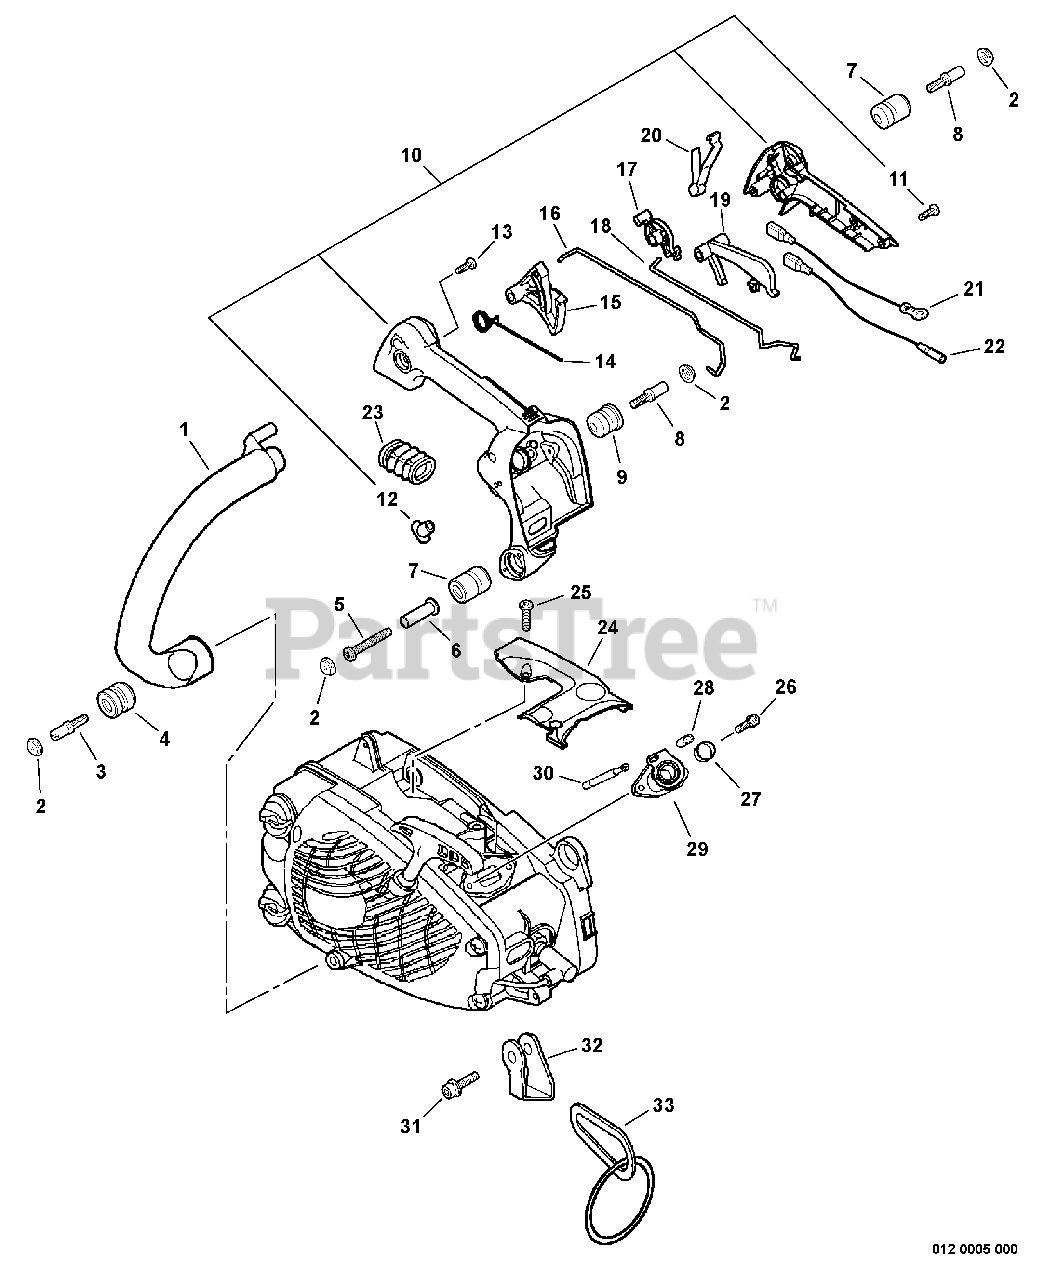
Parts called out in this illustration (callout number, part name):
1	HANDLE - FRONT
2	CAP, CUSHION
5	SCREW - 4X35 -- TAPPING
7	CUSHION
8	STUD, THREADED
9	CUSHION
10	HANDLE SET - REAR
11	SCREW - 4X16
13	SCREW - 5X20 -- TAPPING
14	SPRING, TRIGGER
15	TRIGGER, THROTTLE
16	ROD, THROTTLE
17	LEVER, CHOKE
18	ROD, CHOKE
19	LEVER, TRIGGER LOCKOUT
20	TERMINAL - GROUND
21	LEAD - GROUND
22	LEAD - IGNITION
23	BELLOWS, INTAKE
24	COVER, DUST - GRAY
25	SCREW - 4X12 -- TAPPING
26	SCREW - 5X12
27	COLLAR - 16
28	ADAPTOR
29	BELLOWS, INTAKE
30	PIPE
31	SCREW - 4X25
32	BRACKET, STRAP
33	HANGER KIT
